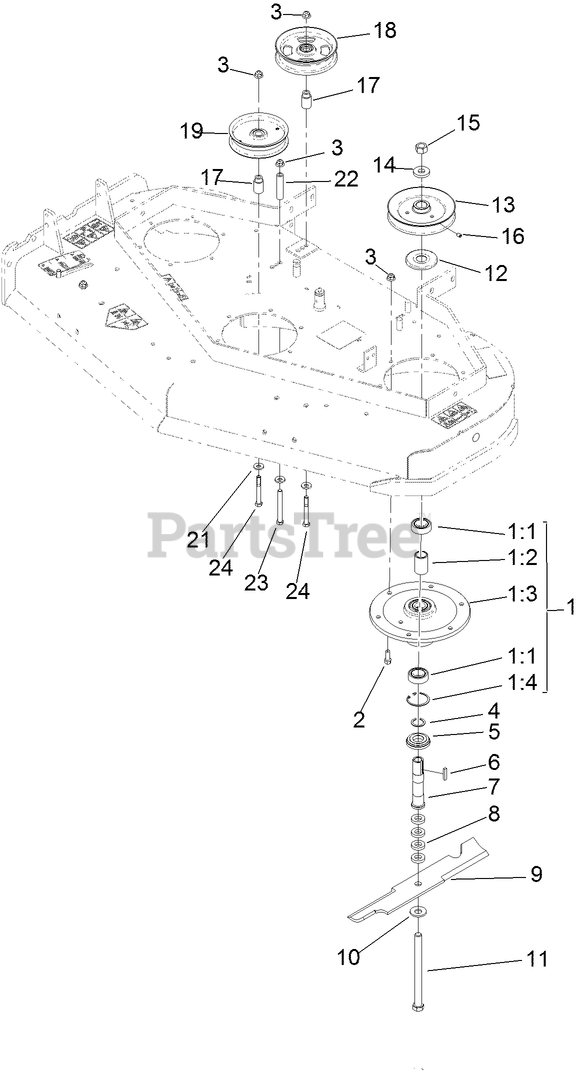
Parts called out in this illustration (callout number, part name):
1	SPINDLE HOUSING ASM
1:1	BEARING-BALL, 1 INCH
1:2	SPACER-BEARING
1:3	HOUSING-SPINDLE
1:4	RING-SNAP
3	NUT-HF, NI
4	WASHER-SPACER
5	SPACER-GUARD, BOTTOM
7	TUBE-SPINDLE, SHORT
8	SPACER
9	BLADE-16.5 INCH (HIGH FLOW)
10	WASHER-SPRING
11	SCREW-CAP, HH
12	GUARD-BEARING, TOP
13	SHEAVE
14	WASHER-RETAINER, SHEAVE
15	NUT-HEX
16	SETSCREW
17	BUSHING-IDLER
18	PULLEY-IDLER,FLAT
19	PULLEY-IDLER
21	WASHER-BELLEVILLE
22	SPACER
23	SCREW-HH
24	SCREW-HH
